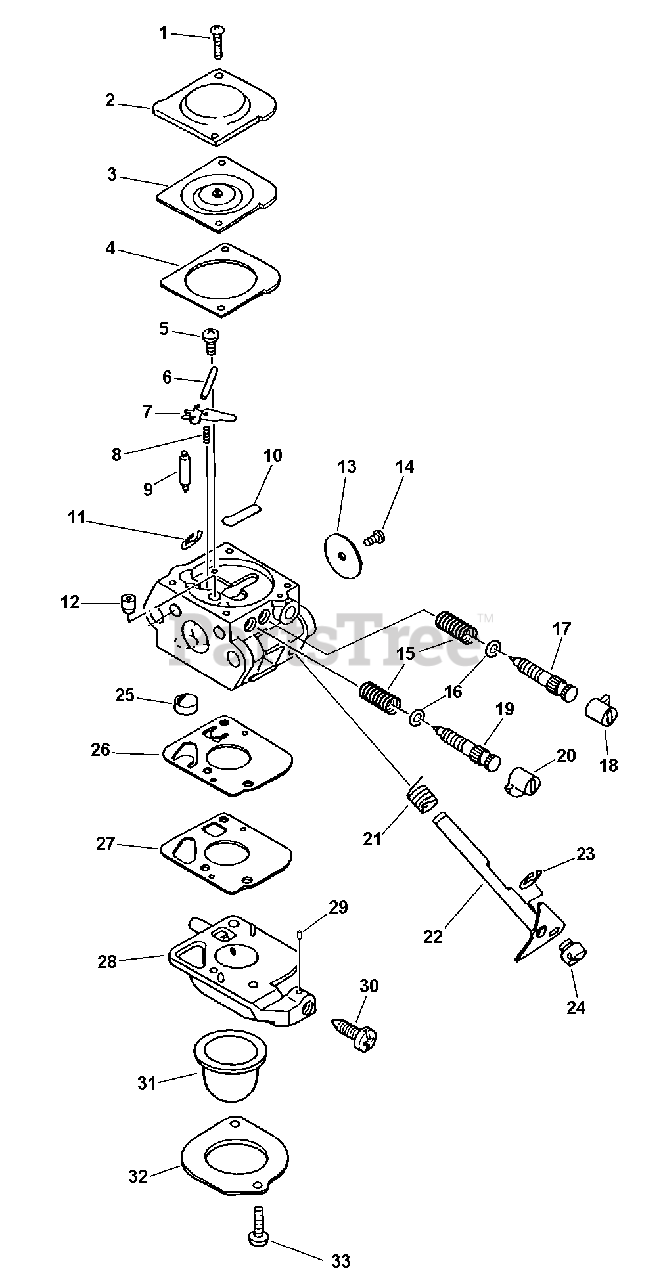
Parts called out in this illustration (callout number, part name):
2	Cover, Metering Diaphragm
3	Diaphragm, Metering
4	Gasket, Metering Diaphragm
6	Pin, Metering Arm
7	Lever, Metering
8	Spring, Metering Lever
9	Valve, Inlet Needle
10	Plug, Welch
12	Nozzle, Check Valve
13	Valve, Throttle
15	Spring, Needle
17	Needle, Lo Speed
18	Cap, Limiter - Lo Speed
19	Needle, High Speed
20	Cap, Limiter - High Speed
21	Spring, Throttle Return
22	Shaft, Throttle
25	Strainer
26	Diaphragm, Fuel Pump
27	Gasket, Fuel Pump
28	Base, Purge
29	Piece, Friction
30	Screw, Idle Adjust
31	Pump, Purge
32	Retainer, Purge Pump
